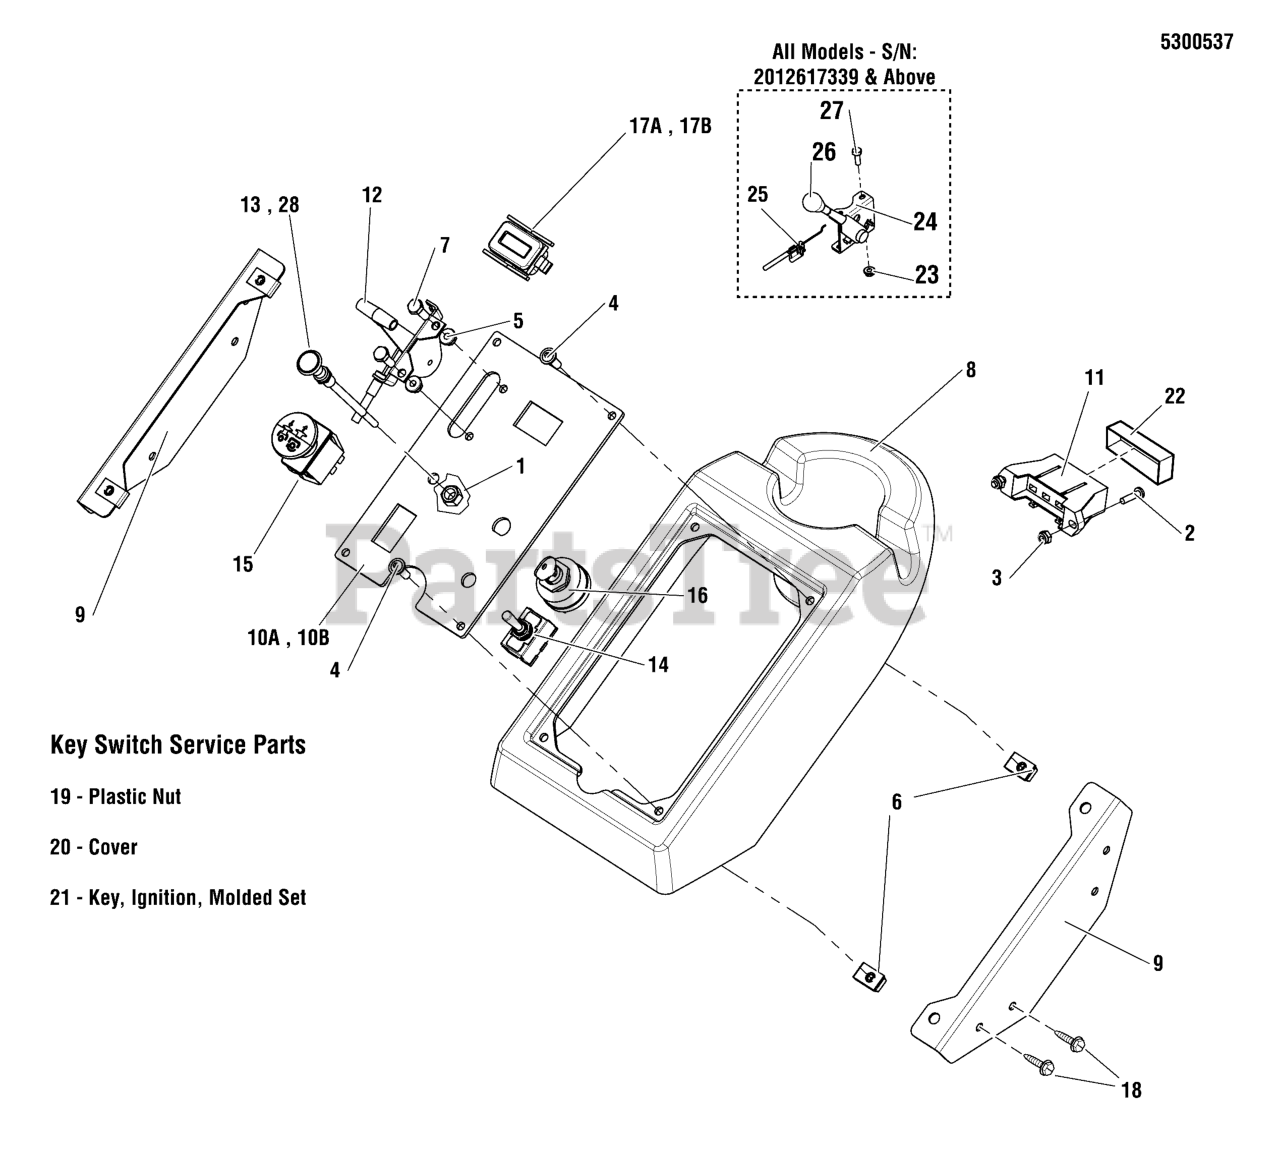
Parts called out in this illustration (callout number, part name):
1	NUT, 3/8-24 HEX (SV)
2	SCREW, #10-24 X 3/4" ROUND PHILLIPS
3	NUT, Hex, Nylon Lock, #10-24
5	NUT, 1/4-20 Hex Nylock Flange
6	BODY CLIP, 1/4-20 X 1/2" DEEP
7	BOLT, 1/4"-20 X 3/4" GD5 YZ
8	BEZEL, 3 WHEEL RIDER
9	PLATE, MOUNT, DASH - RED
11	FUSE, BLOCK (SEE ELECTRICAL GROUPS)
12	CABLE, THROTTLE CONTROL, 54"
13	CABLE, Choke Control, 57"
14	Switch, Electric Actuator
15	SWITCH, BLADE ENGAGEMENT
16	SWITCH, IGNITION, 6 POST
18	BOLT, Self-Tapping, 1/4-20 x 3/4
22	COVER, VINYL, FUSE BLOCK
23	NUT, Hex, Nylon Lock, #10-24
24	LEVER, THROTTLE CONTROL, HEAVY-DUTY
25	CABLE, THROTTLE, 52"
26	THROTTLE CONTROL HANDLE/KNOB
27	SCREW, #10-24 X 3/4" ROUND PHILLIPS
28	CABLE, CHOKE CONTROL, 51" (Z)
